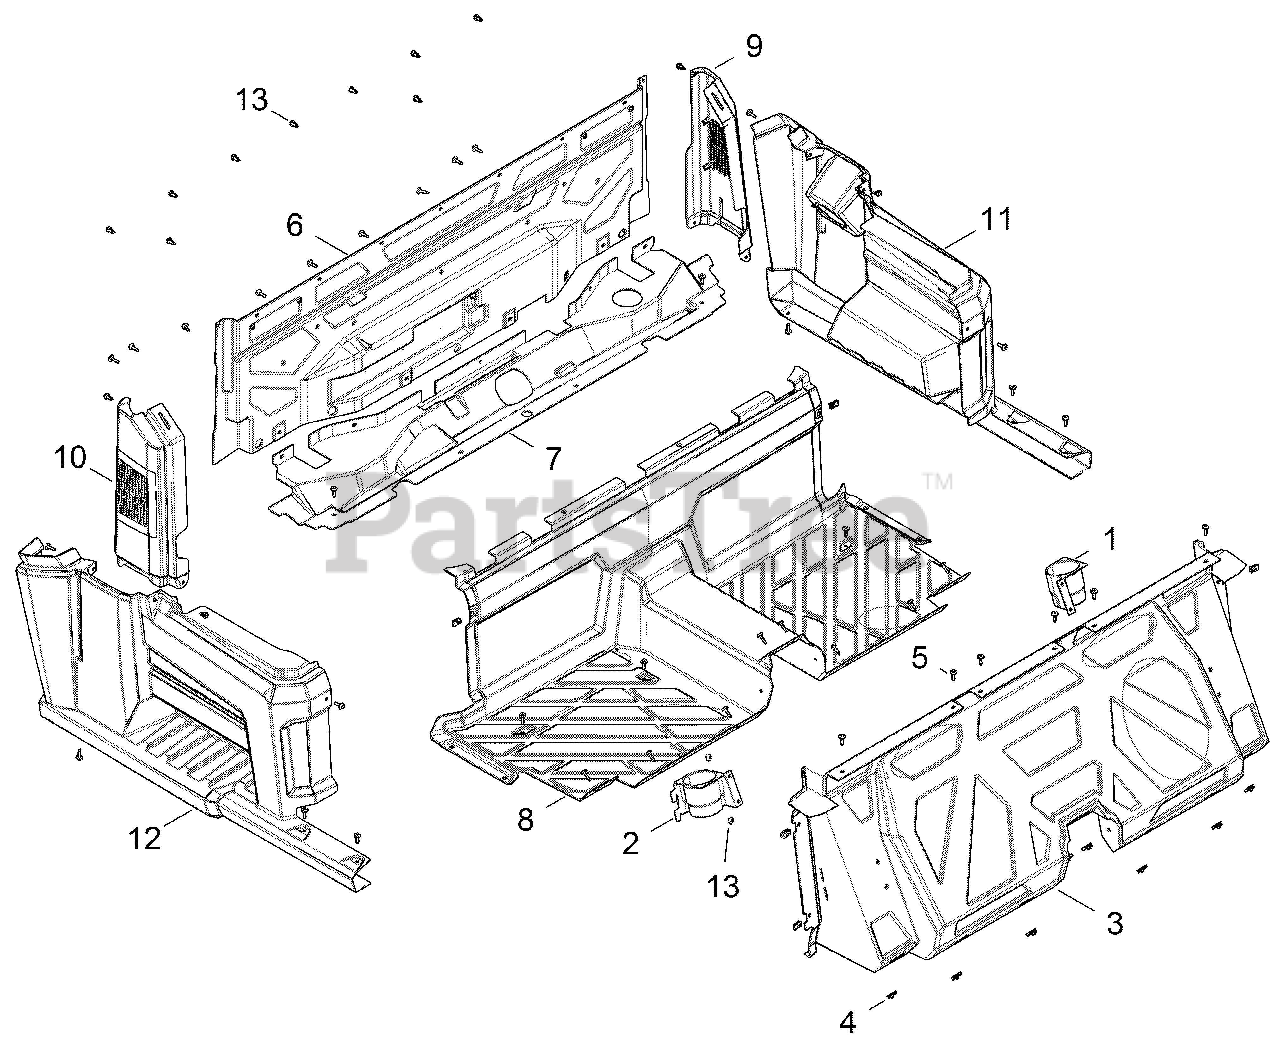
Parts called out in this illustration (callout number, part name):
1	HOLDER, CUP, LH, BLACK
2	HOLDER, CUP, RH,BLK
3	FLOOR,PANEL,REAR,BLK
4	CLIP-U SPEED NUT
5	SCR-TXTH-M6X1.0X25 RIE
6	PANEL-CLOSEOFF,REAR,BLK
7	PANEL-CLOSEOFF,LOWER,BLK
8	FLOOR,REAR,BLK
9	ASM-FENDER-REAR,UPPER,LH,BLK
10	ASM-FENDER-REAR,UPPER,RH,BLK
11	FENDER,REAR,W/ROCKER,CREW, LH
12	FENDER,REAR,W/ROCKER,CREW,RH
13	RIVET-TUFLOK,.315-.325X.787 (5
